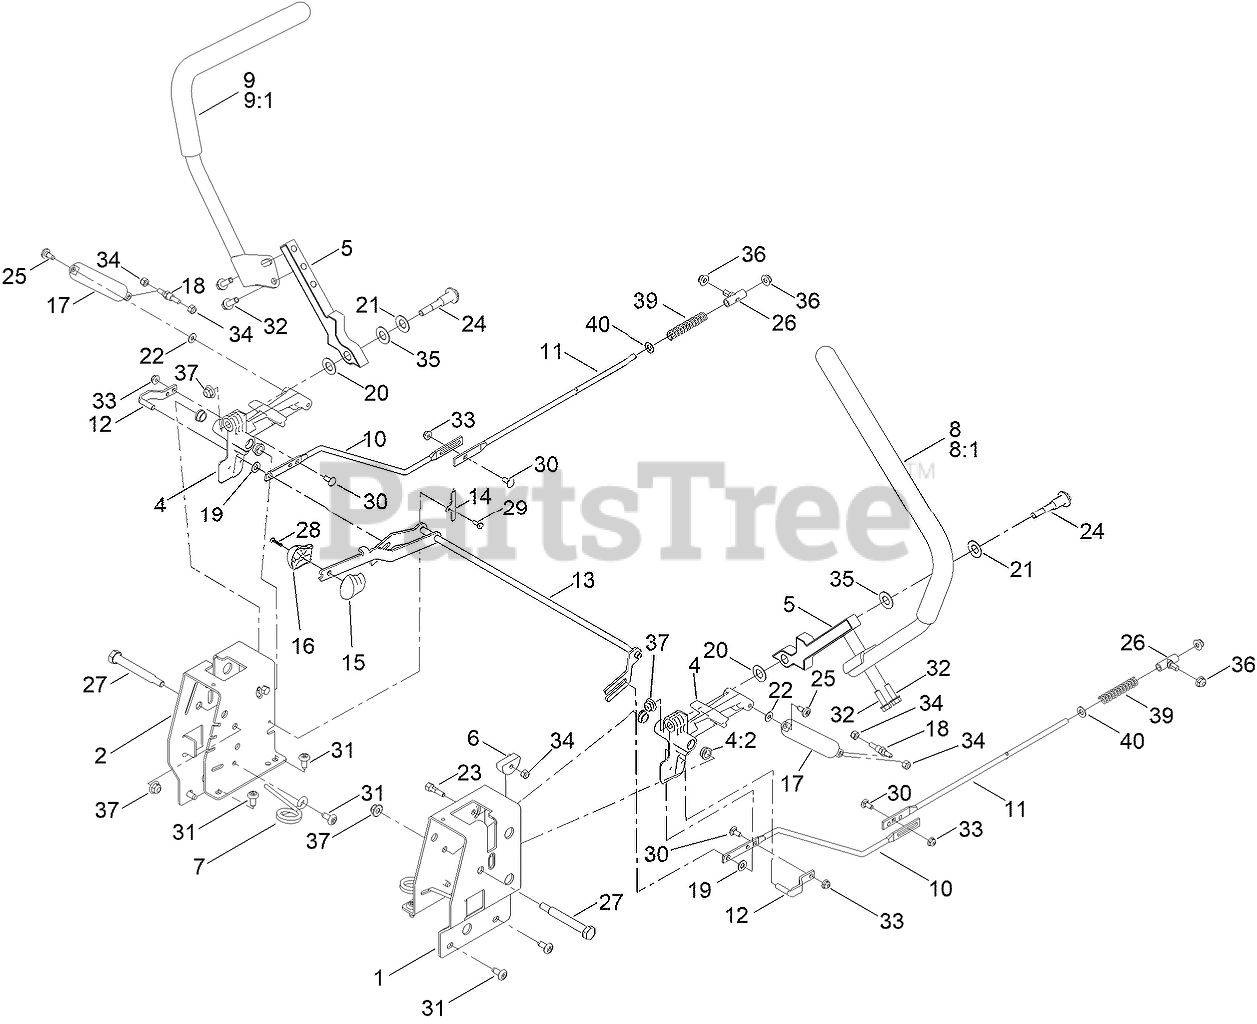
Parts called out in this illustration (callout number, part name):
1	PLATE-CONTROL BOX, LH
2	PLATE-CONTROL BOX, RH
4	ACTUATOR ARM ASM
4:2	BUSHING-FLANGE
5	ARM-CONTROL
6	ECCENTRIC
7	SPRING-TORSION
8	HANDLE-CONTROL, LH
9	HANDLE-CONTROL, RH
10	ROD-HYDRO, FRONT
11	ROD-HYDRO, REAR
12	PIN-ROD, HYDRO
13	SPEED CONTROL ASM
14	PLATE-RETAINER
15	KNOB-RH
16	KNOB-LH
17	DAMPER-NON CAVITATING
18	STUD-DAMPER
19	SPACER-NYLON
20	WASHER-NYLON
21	WASHER-BELLEVILLE
22	WASHER
23	BOLT-PIVOT, ECCENTRIC
24	BOLT-PIVOT
25	SCREW-SHOULDER
26	MOUNT-ROD, HYDRO
27	BOLT-PIVOT
28	SCREW-PPH
29	SCREW-TAPTITE
30	BOLT-CARR
32	SCREW-HHF
33	NUT-HF
34	NUT-HEX
35	WASHER
36	NUT-HF
37	NUT-HF, NI
39	SPRING-COMPRESSION
40	WASHER-PLAIN
